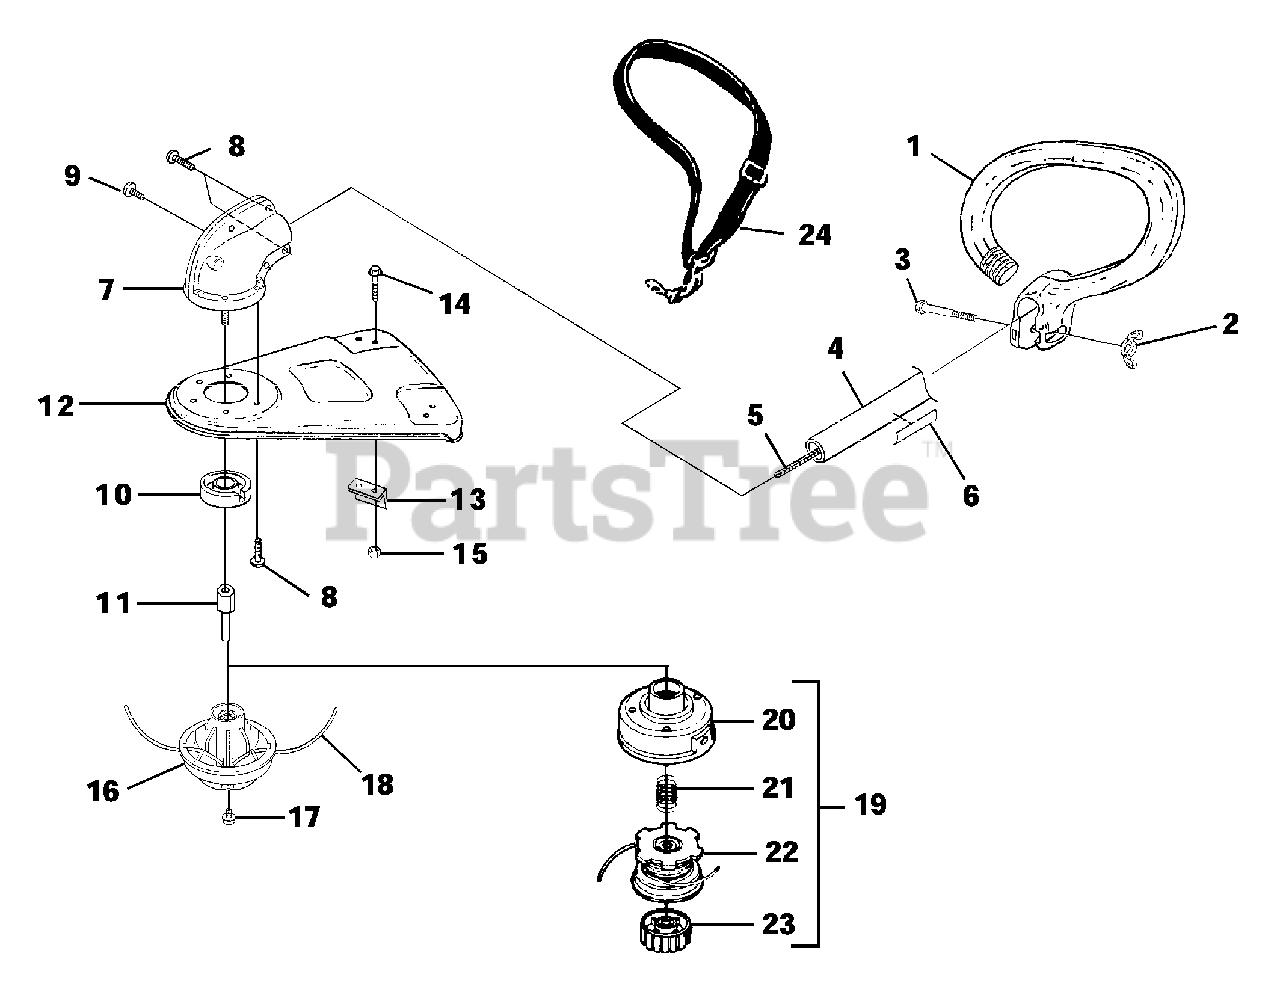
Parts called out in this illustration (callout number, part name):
1	HANDLE-Anti-Vibe
2	NUT-Wing, Washer Faced (1/4-20)
3	SCREW-Cap Hex Hd. (1/4-20 x 2")
4	DRIVESHAFT HOUSING ASSY.
5	SHAFT-Flexible
6	DECAL-Warning
7	GEARHEAD
8	Screw, Taptite Hex Hd. (10-24 x 1/2")
9	Screw-Hex Hd. (10-24 x 5/8")
10	WASHER-Flanged
11	ADAPTER-Shaft
12	GRASS DEFLECTOR KIT
13	BLADE-Cut-off
14	SCREW-Mach.Hex Hd. (10-24 X 3/8")
15	NUT-Lock Hex (10-24)
16	STRINGHEAD-Pro-Cut w/line (UT20699, UT20703, UT20701, UT20730, UT20729, UT20737)
17	SCREW (5/16-18 x 5/8")
18	LINE-Replacement
19	STRINGHEAD-Complete (.080") (UT20704, UT20738, UT20734R, UT20827)
20	HOUSING & EYELET (Dual Line)
21	SPRING-Compression
22	SPOOL & STRING (.080")
23	RETAINER-Spool (R.H. Thread, Black)
24	HARNESS
